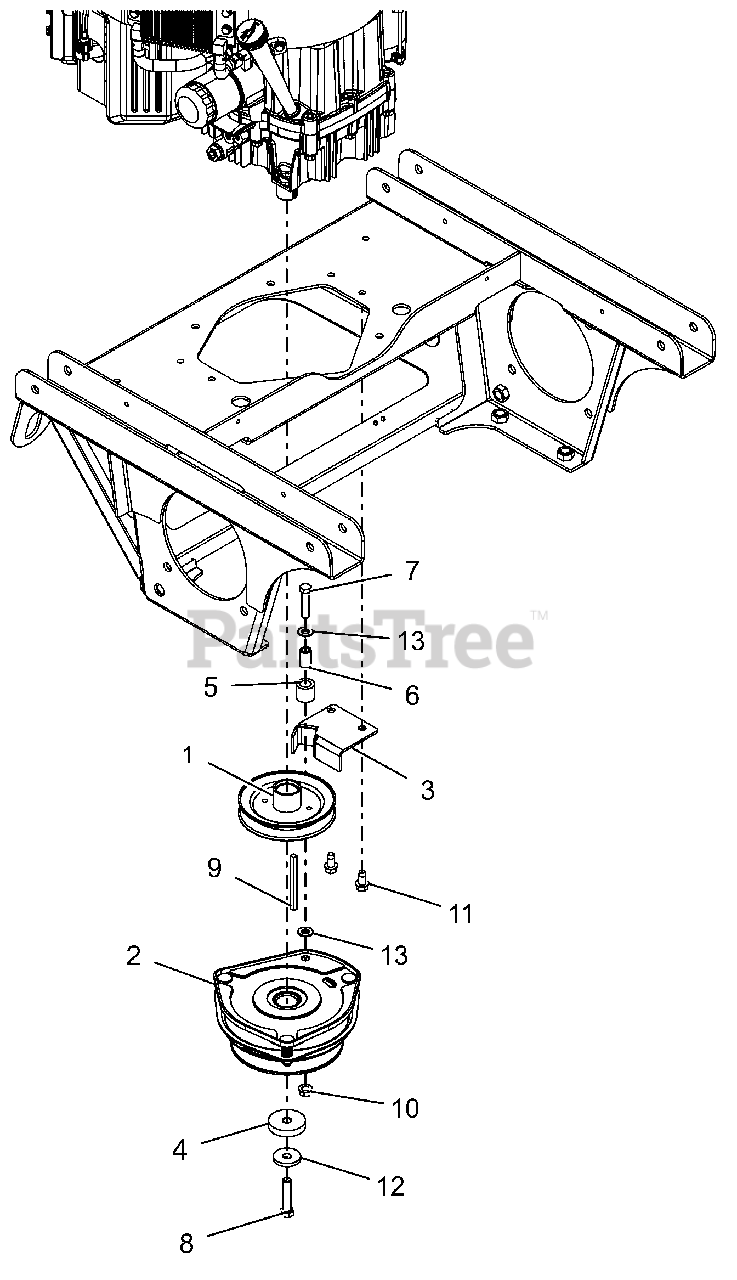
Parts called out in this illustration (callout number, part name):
1	SHEAVE-ENGINE 1.127ID X 5.25OD
2	CLUTCH, ELE-OGURA GT3.5-VP01R
3	CLUTCH STOP WLDMT - BLACK
4	SPACER, .450X2.00X.396
5	BUMPER,RUBBER .62X1.0X.88 LG
6	BUSH.,S.391X.622X.950 ST
7	@BLT-HEX .38-16X1.75 GR5 YWZC
8	BLT-HEX .438-20X2 G8YZ NYTORQ
9	KEY-SQ. .25X3.50X.25 SAE
10	@NUT-LK-TOP-FLG .38-16 YWZC
11	@SCR-TAP .38-16X.75 HWH TR YWZ
12	WASHER, 7/16" SPRING DISK
13	@WSHR-FL-STL.406X.812X.065 YWZ
